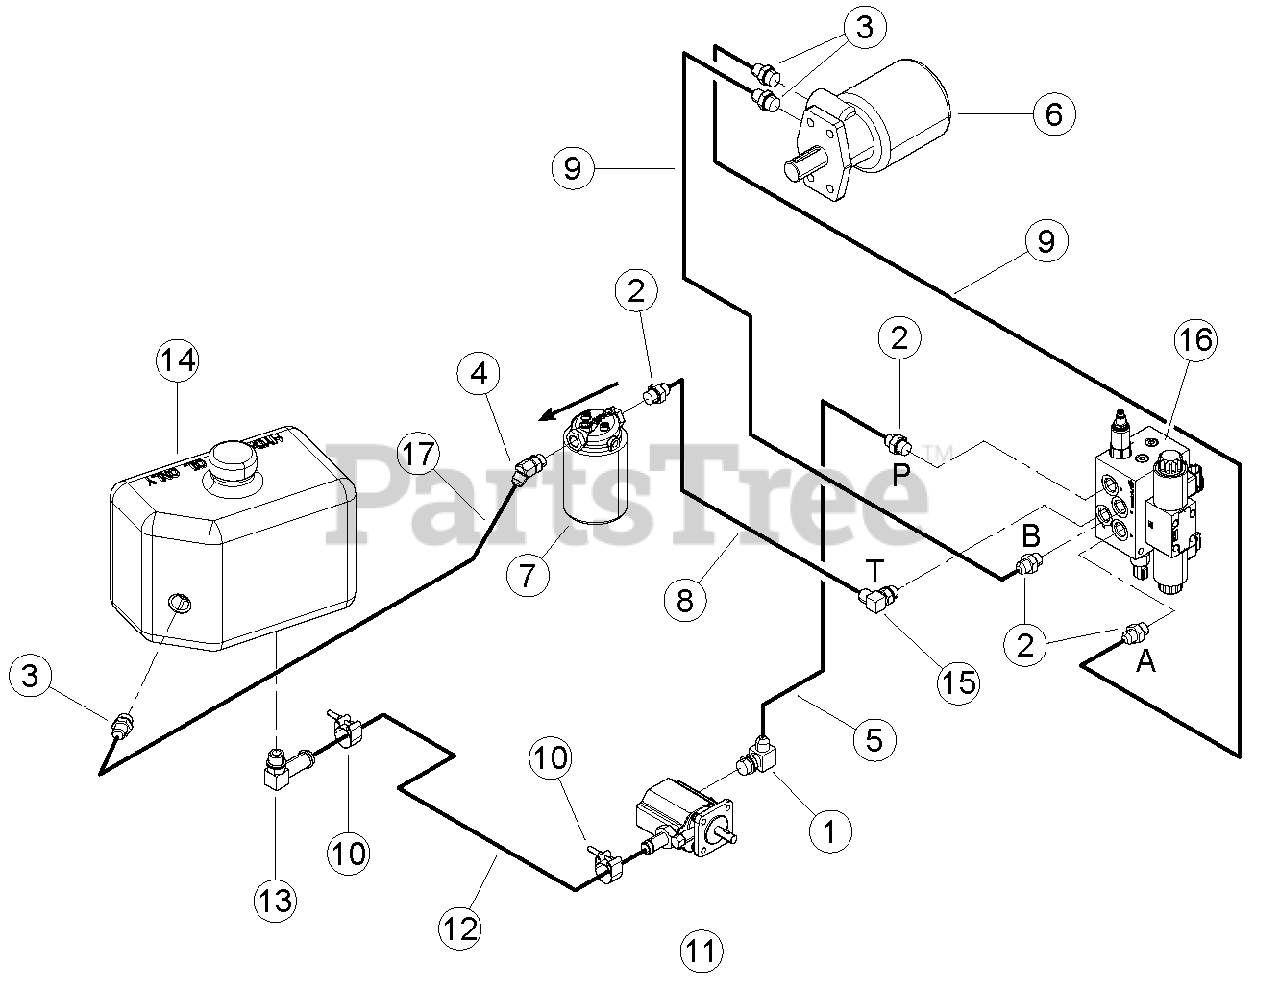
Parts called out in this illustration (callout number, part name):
1	ADAPTER, -10 MORING / -8 MJIC 90 DEG.
2	ADAPTER, -8 MORING / -8 MJIC
3	ADAPTER, -10 MORING / -8 MJIC
4	ADAPTER, -8 MORING / -8 MJIC 45 DEG.
5	HOSE ASSEMBLY, -8 FMJIC / -8 FMJICSW X 8-1/2
6	MOTOR, 45 CU. IN. HYDRAULIC
7	FILTER, SPIN ON (ARROW ON TOP OF FILTER HEAD INDICATES DIRECTION OF FLOW)
8	HOSE ASSEMBLY, -8 FMJIC / -8 FMJIC 90 X 21 INCH
9	HOSE ASSEMBLY, -8 FMJIC / -8 FMJIC 90 X 61 INCH
10	CLAMP, 1 INCH OD. HOSE T-BOLT
11	PUMP, 2 STAGE CW HI/LO 0.605 DISP.
12	HOSE, .75 ID X 28 IN 100R4 HYD
13	ADAPTER, -10 MORING/.75 90 DEG. HOSE
14	TANK, OIL RESERVOIR
15	ADAPTER, -8 MORING / -8 MJIC 90 DEG.
16	ASSEMBLY, HYDRAULIC FEED FLOW VALVE
17	HOSE, 3/8 X 35 -8 FJICSW
